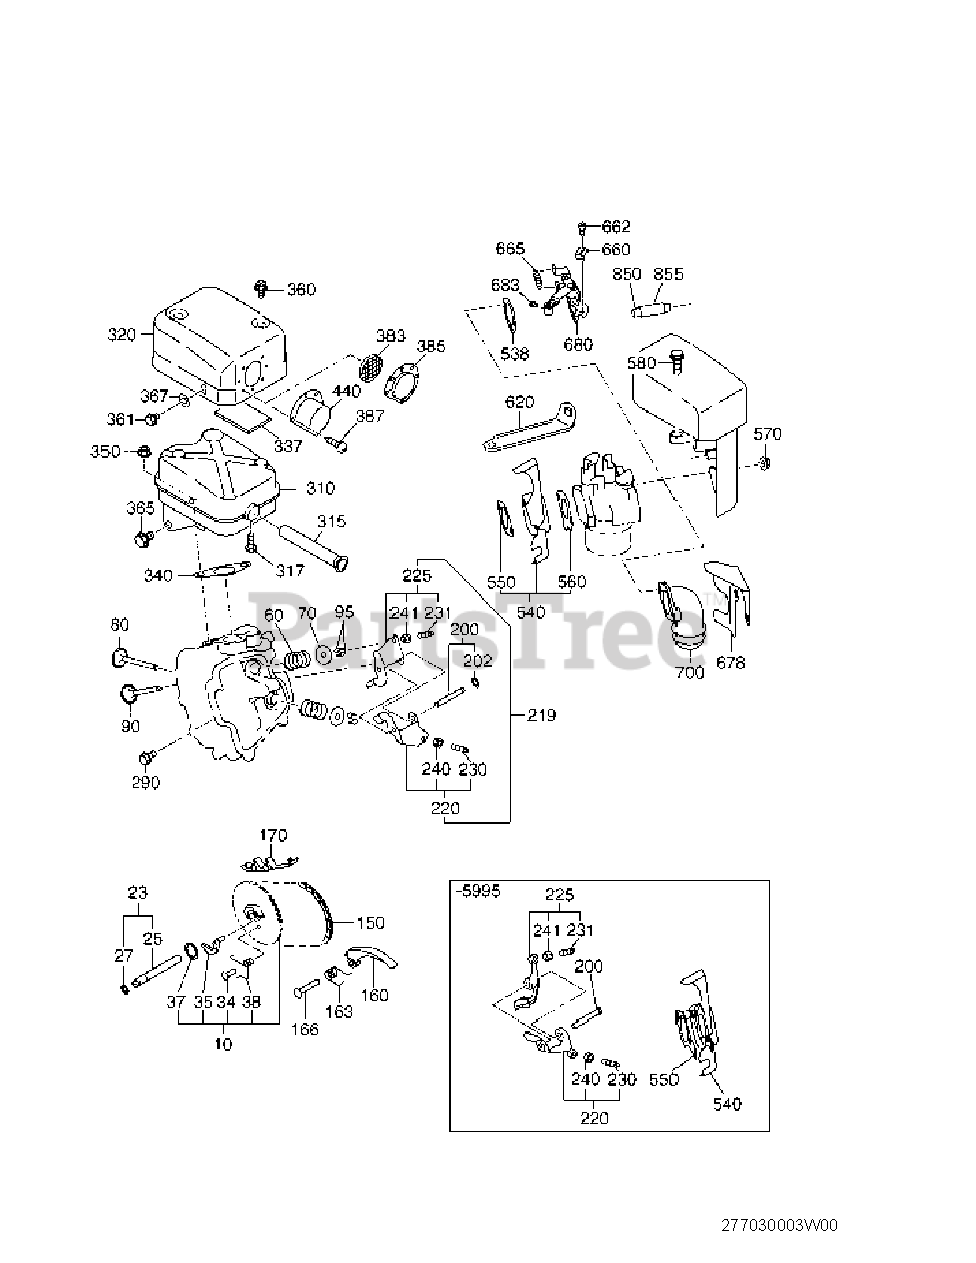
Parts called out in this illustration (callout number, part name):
23	PIN(CAM SHAFT)CP
70	SPRING RETAINER
150	TIMING CHAIN CP
163	SPRING(TENTIONER)
166	PIN(TENTIONER)
200	PIN(ROCKER) CP
219	ROCKER ARM AY SET
315	SPARK ARRESTER CP
320	MUFFLER COVER CP
340	GASKET(MUFFLER)
550	GASKET2(INSULATOR)
560	GASKET1(INSULATOR)
